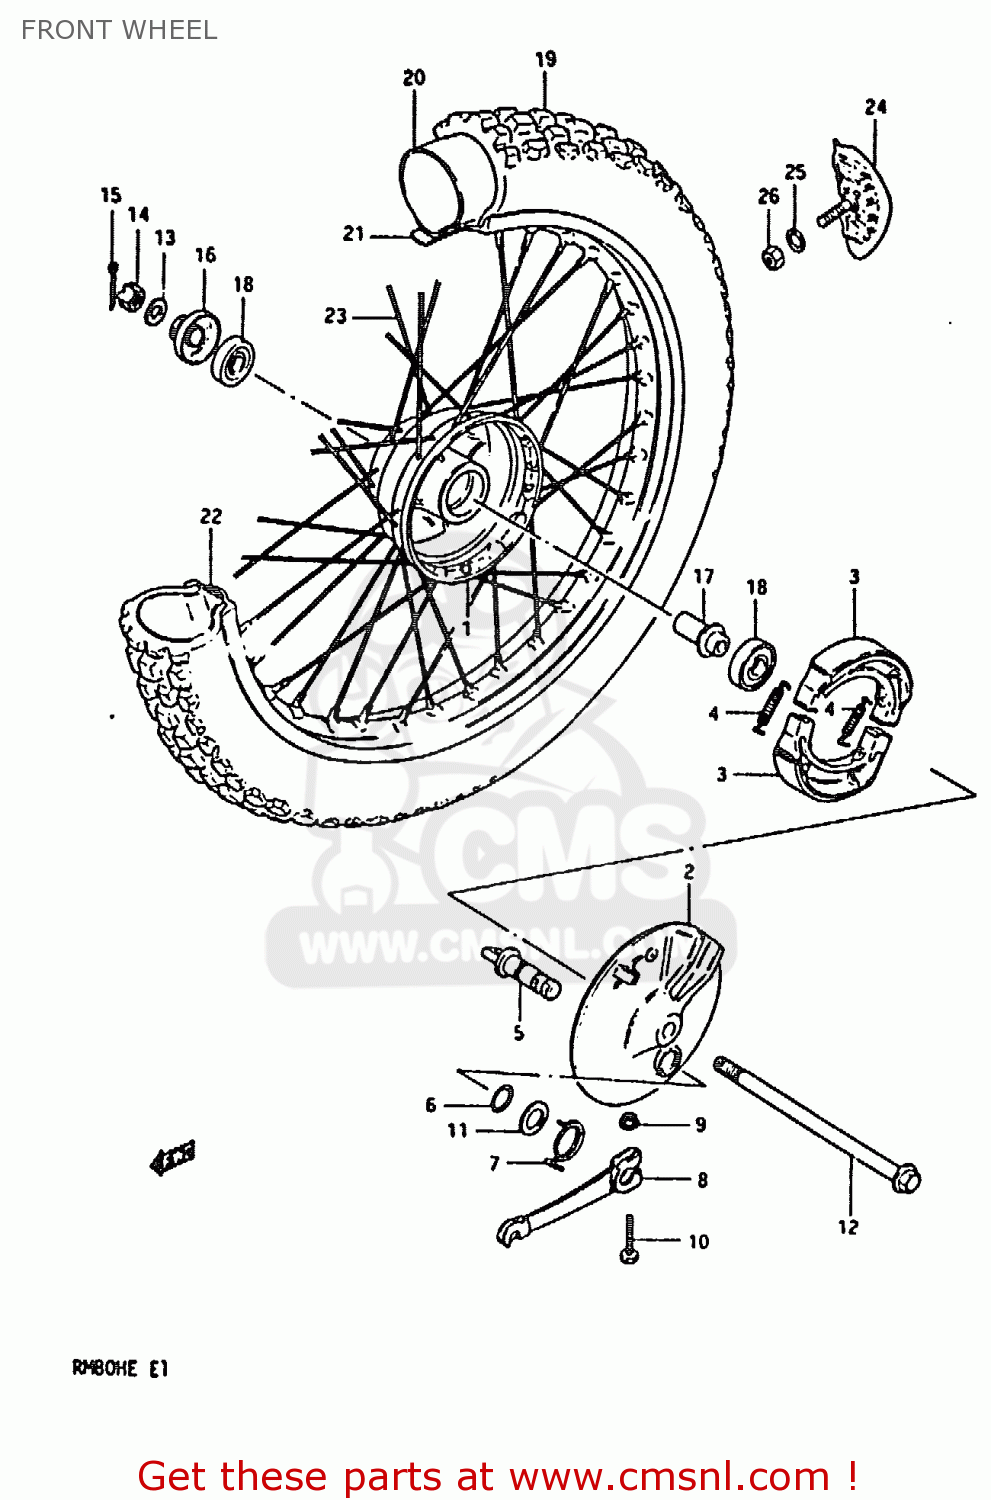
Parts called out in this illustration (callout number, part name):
1	DRUM,FRONT HUB
2	PANEL,FRONT HUB
3	SHOE,BRAKE
4	SPRING
5	CAM,FR BRAKE
6	O RING(D:2.5,ID:11.4)
7	SPRING
8	LEVER, BRAKE CAM
9	NUT
10	BOLT
11	WASHER
12	AXLE, FRONT
13	WASHER
14	NUT 12MM
15	COTTER PIN
16	SPACER, AXLE
17	SPACER,FRONT HUB BEARING
18	BEARING
19	TIRE (2.75-21)
20	TUBE
21	PROTECTOR,WHEEL,INNER
22	RIM,FRONT WHEEL
23	SPOKE SET,FRONT
24	STOPPER,BEAD
25	WASHER
26	NUT
